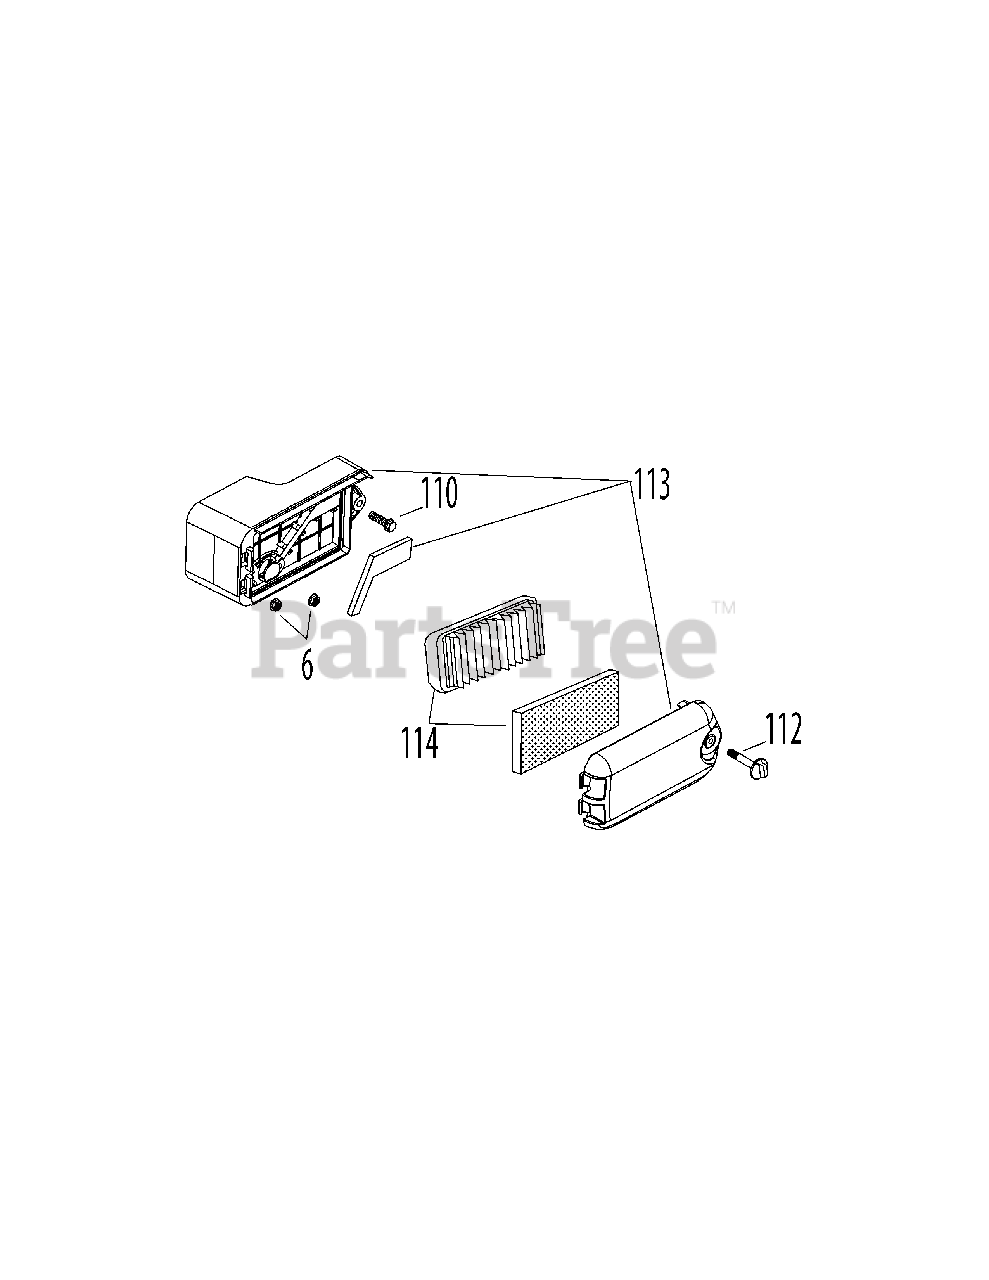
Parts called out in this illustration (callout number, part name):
6	Nut M6 X 10 Mm
110	A/F Base Bolt M6×30
112	Air Filter Cover Thumb Screw
113	Air Cleaner Housing Ass'y Comp
114	Air Filter, Sponge Pre-Filter
